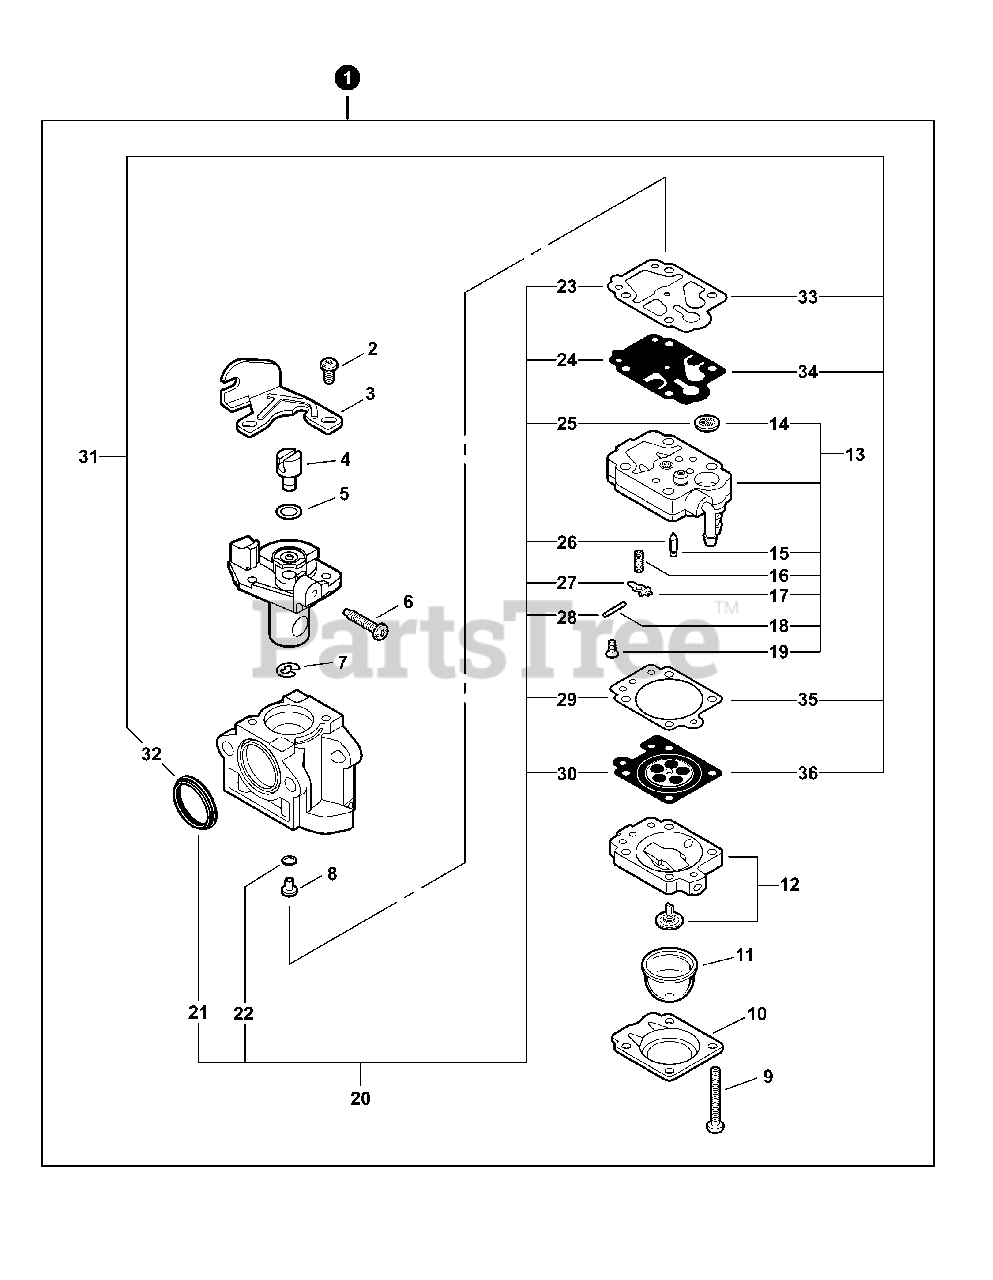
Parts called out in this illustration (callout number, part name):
1	CARBURETOR - WYJ-330A
3	BRACKET, THROTTLE CABLE
8	JET, MAIN
10	RETAINER, PURGE BULB
11	BULB, PURGE
12	BODY ASSY, PURGE
13	BODY ASSY, PUMP
14	STRAINER
15	VALVE, INLET NEEDLE
16	SPRING, METERING LEVER
17	LEVER, METERING
18	PIN, METERING LEVER
20	REPAIR KIT, CARBURETOR
21	RING, PACKING
22	O-RING
23	GASKET, PUMP
24	DIAPHRAGM, PUMP
25	STRAINER
26	VALVE, INLET NEEDLE
27	LEVER, METERING
28	PIN, METERING LEVER
29	GASKET, METERING
30	DIAPHRAGM, METERING
31	GASKET / DIAPHRAGM KIT
32	RING, PACKING
33	GASKET, PUMP
34	DIAPHRAGM, PUMP
35	GASKET, METERING
36	DIAPHRAGM, METERING
